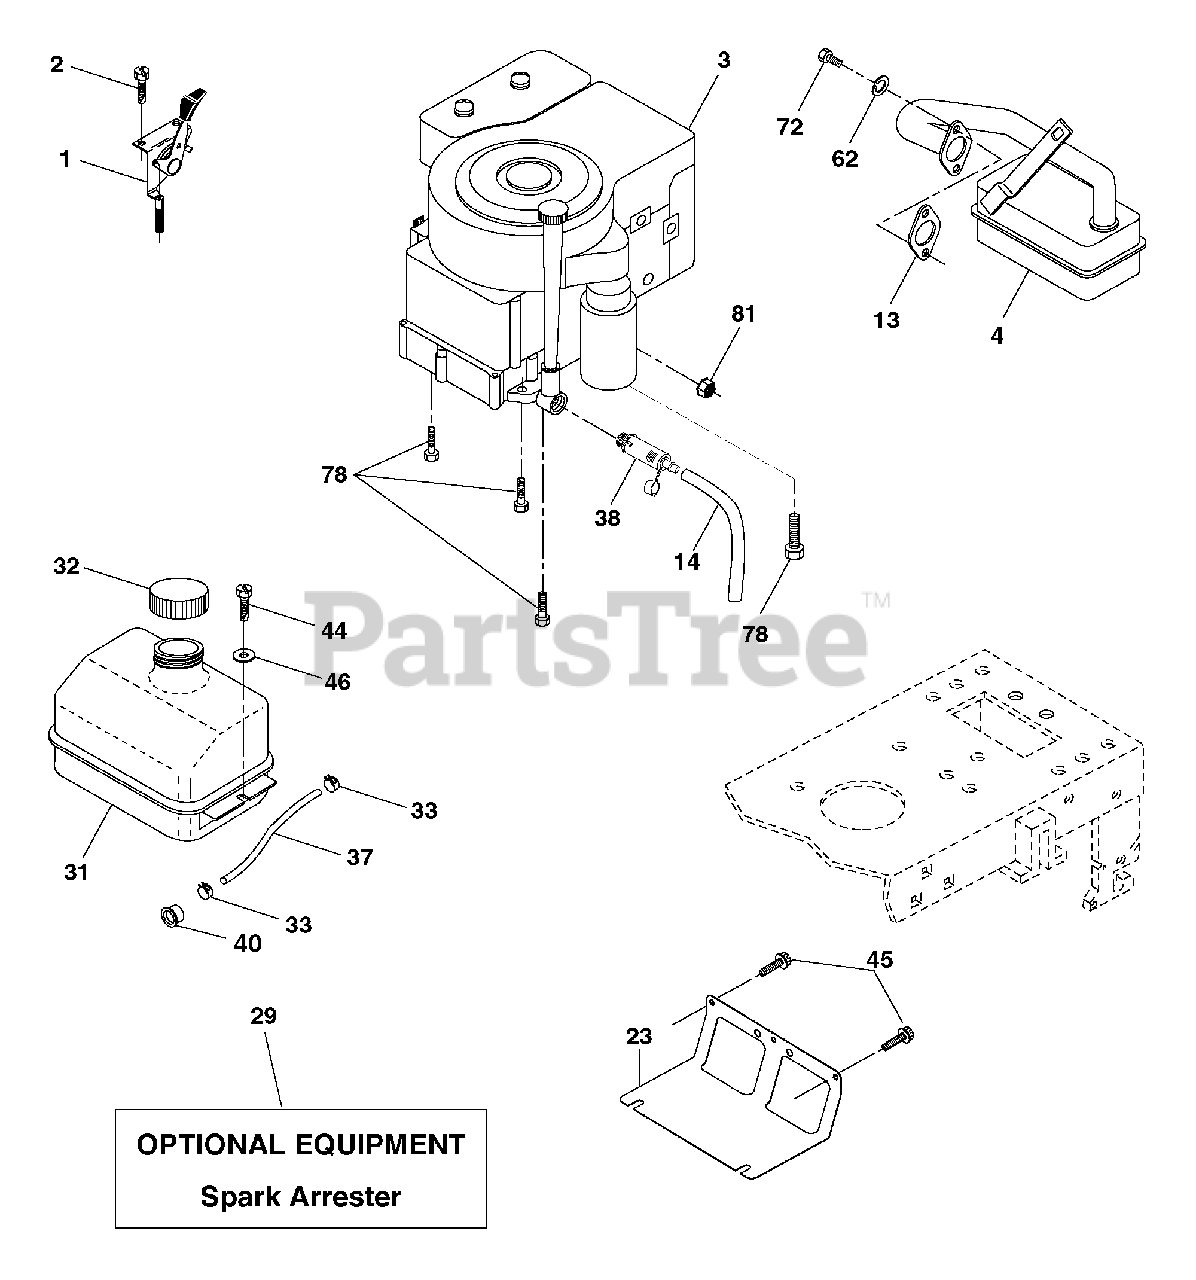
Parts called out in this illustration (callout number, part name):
1	Control Throttle /Choke Flag
2	Screw Hex Thd Cut 1/4-20 x 1/2
4	Muffler Exhaust B&S Lt
13	Gasket 1 313 Id Tin Plated
14	Tube Drain Oil Easy
23	Shield Browning/Debris Guard
29	Arrestor Spark
31	Tank Fuel 1 25 Fr
32	Cap Asm Fuel
33	Clamp Hose Blk
37	Line Fuel 20"
38	Plug Drain Oil Easy
40	Bushing Snap Nyl Blk Fuel Line
44	Screw Hexwsh Thdrol 1/4-20 x 3/4
45	Screw Hex Wsh Thdrol 3/8-16
46	Washer 9/32 X 7/8 X 16 Ga.
62	Washer Split
72	Screw Socket Head 5/16-18 x .75
78	Screw Thdrol 3/8-16 x 1-1/4
81	Nut Keps Hex 1/4-20 unc
